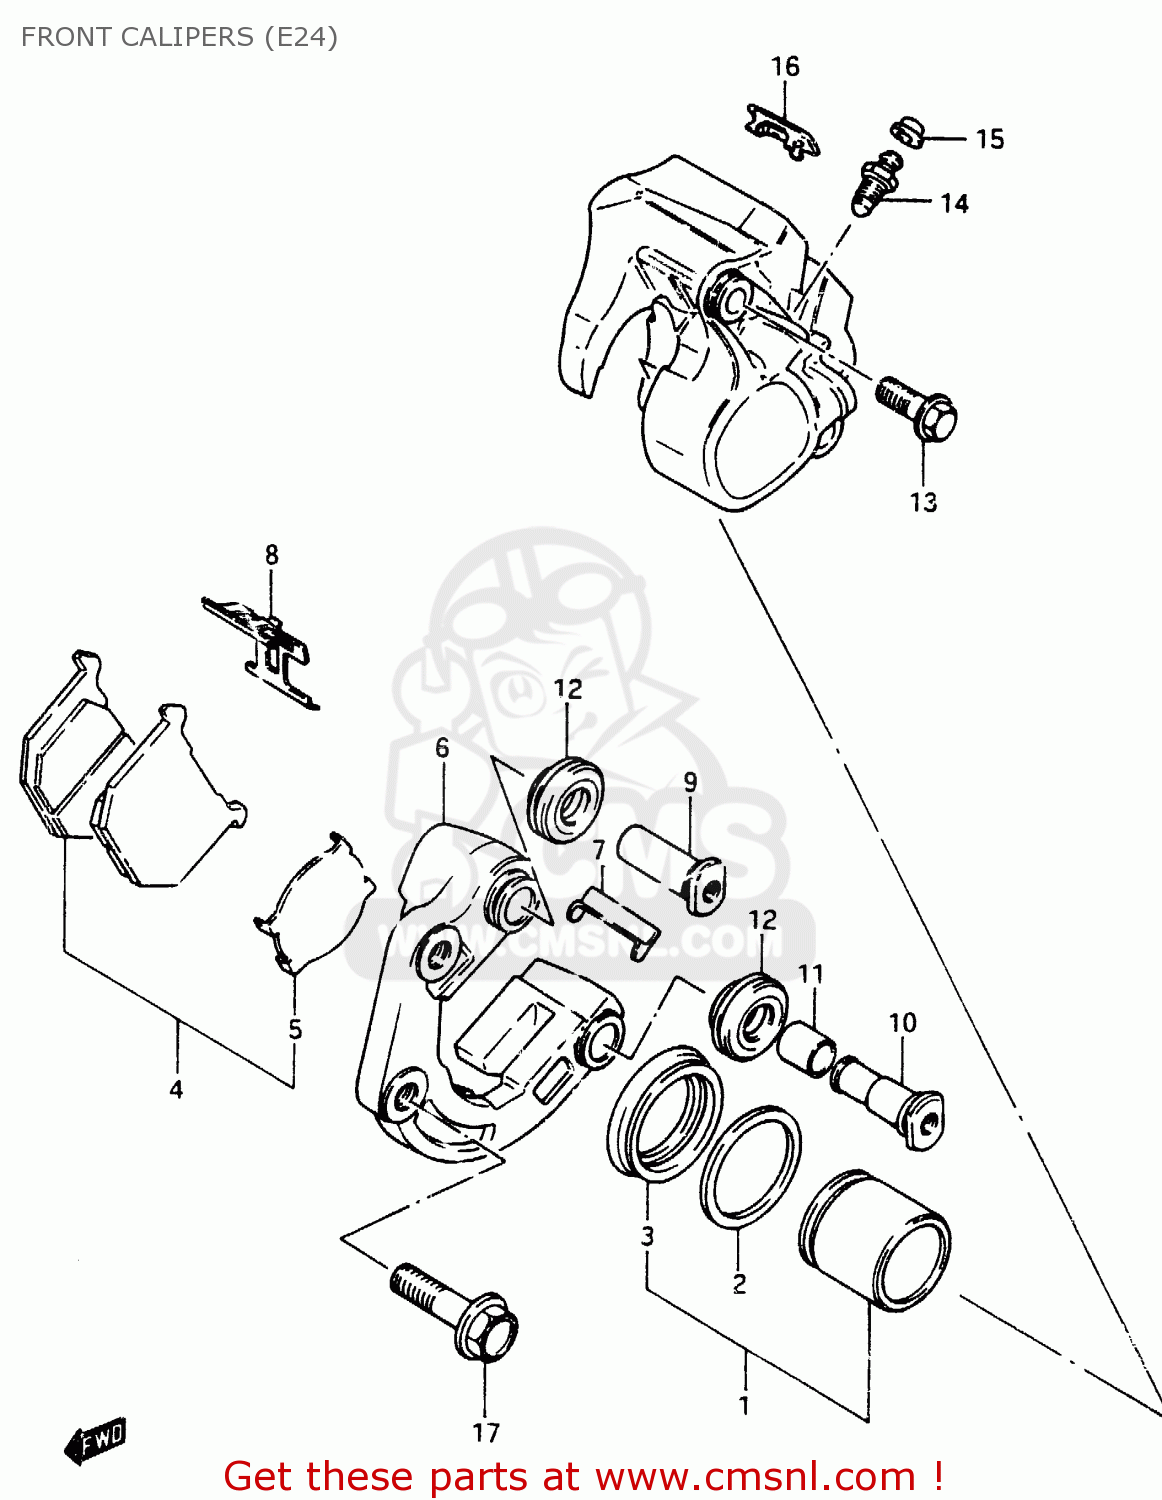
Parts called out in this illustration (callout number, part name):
1	PISTON SET
2	SEAL,PISTON
3	BOOT,PISTON
4	PAD & SHIM SET (NAS)
5	SHIM,PAD
6	CARRIER,CALIPER,LEFT
7	GUIDE,PAD
8	SPRING,PAD
9	AXLE NO.1
10	AXLE NO.2
11	BUSH,AXLE
12	BOOT,AXLE
13	BOLT
14	BLEEDER
15	CAP,BREATHER
16	COVER
17	BOLT 10X40
